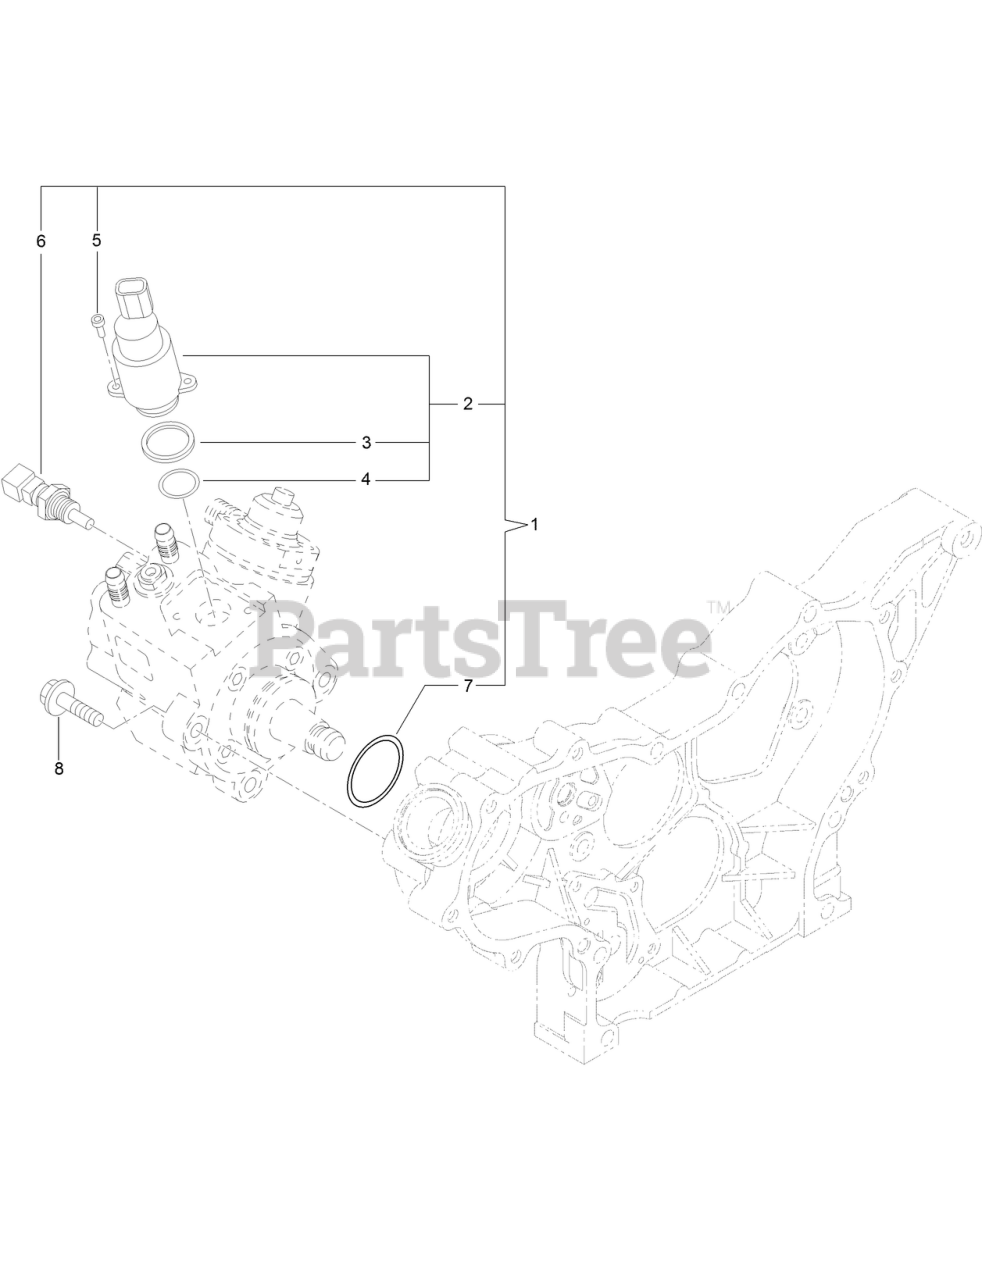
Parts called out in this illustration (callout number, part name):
1	FUEL PUMP ASM
2	VALVE ASM
3	RING-SEALING
4	O-RING
6	SENSOR-TEMPERATURE
7	O-RING
